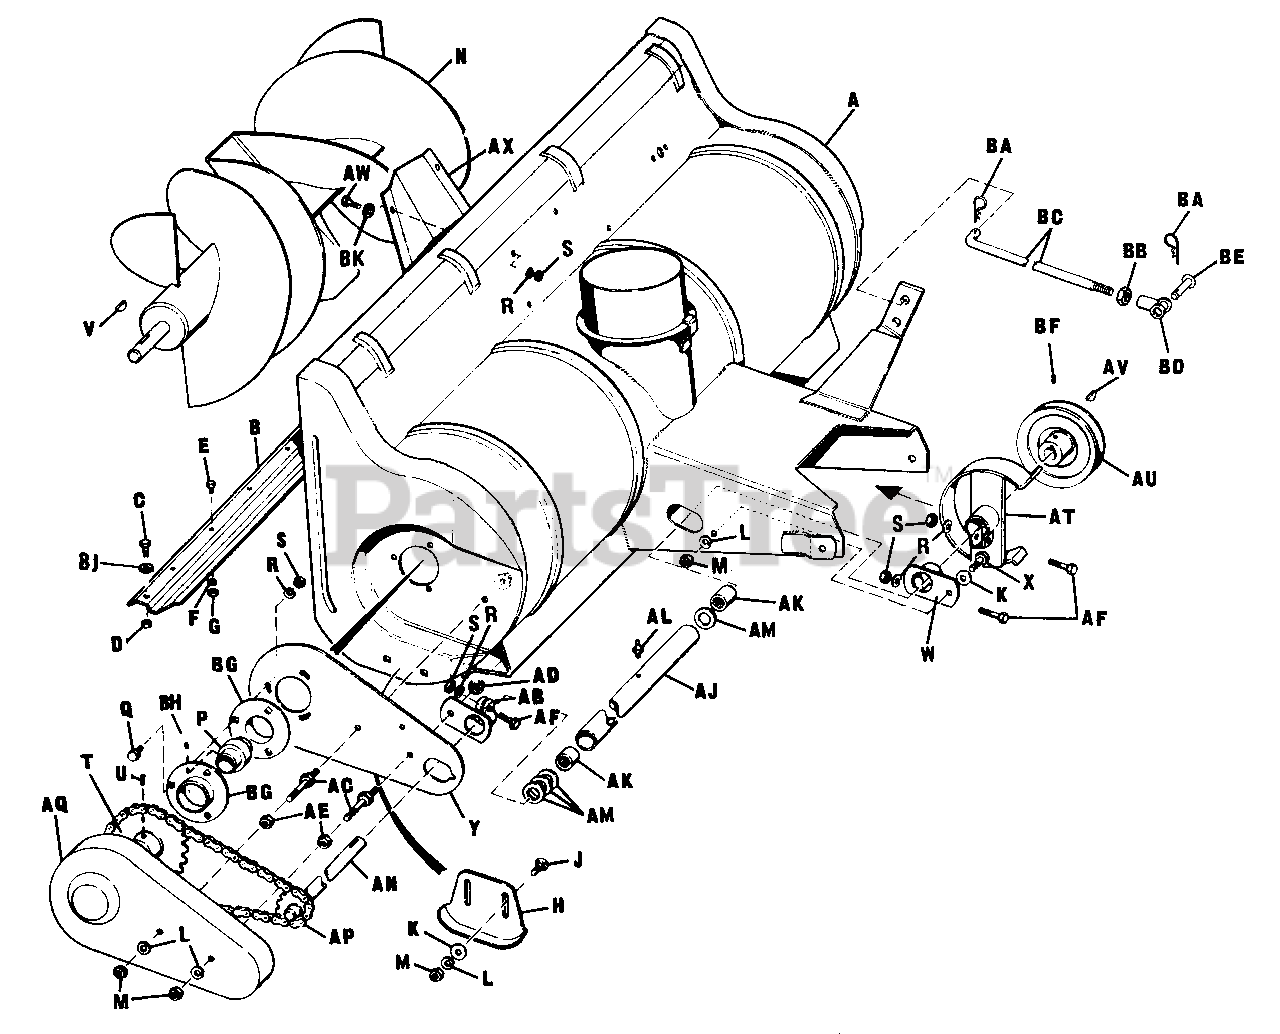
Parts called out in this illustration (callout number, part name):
A	Body Assembly
B	Body Scraper
C	Hex. Cap Screw, 5/16"-18 x 5/8"
D	Full Lock Hex. Nut, 5/16"-18
E	Hex. Cap Screw, 1/4"-20 x 5/8"
F	Lock Washer, 1/4"
G	Full Hex. Nut, 1/4"-20
J	Carriage Bolt, 3/8"-16 x 3/4"
K	Plain Washer, 3/8"
L	Lock Washer, 3/8"
M	Full Hex. Nut, 3/8"-16
N	Rotor Assembly
P	Bearing Cartridge
Q	Hex. Cap Screw, 5/16"-18 x 3/4"
R	Lock Washer, 5/16"
S	Full Hex. Nut, 5/16"-18
T	Rotor Sprocket
U	Set Screw, 5/16"-18 x 5/16"
W	Support Assembly Clamp
X	Hex. Cap Screw, 3/8"-1 x 1"
Y	Side Plate
AB	Support Assembly Clamp
AD	Nut, Flange, 3/8"-16
AE	Full Lock Hex. Nut, 3/8"-16
AF	Hex. Cap Screw, 5/16"-18 x 1-1/2"
AJ	Bearing Housing
AK	Needle Bearing
AL	Grease Fitting
AN	Shaft Assembly
AQ	Chain Guard
AT	Belt Guard Assembly
AV	Key, 3/16" Dia. x 3/4"
AW	Hex. Cap Screw, 5/16"-18 x 5/8"
BA	Spring Clip
BB	Full Hex. Nut, 1/2" x 20
BC	Front Lift Rod
BD	Adjusting End Yoke
BF	Set Screw, 1/4"-28 x 1/4" lg.
BG	Bearing Flange
BH	Set Screw
BK	Plain Washer, 5/16"
